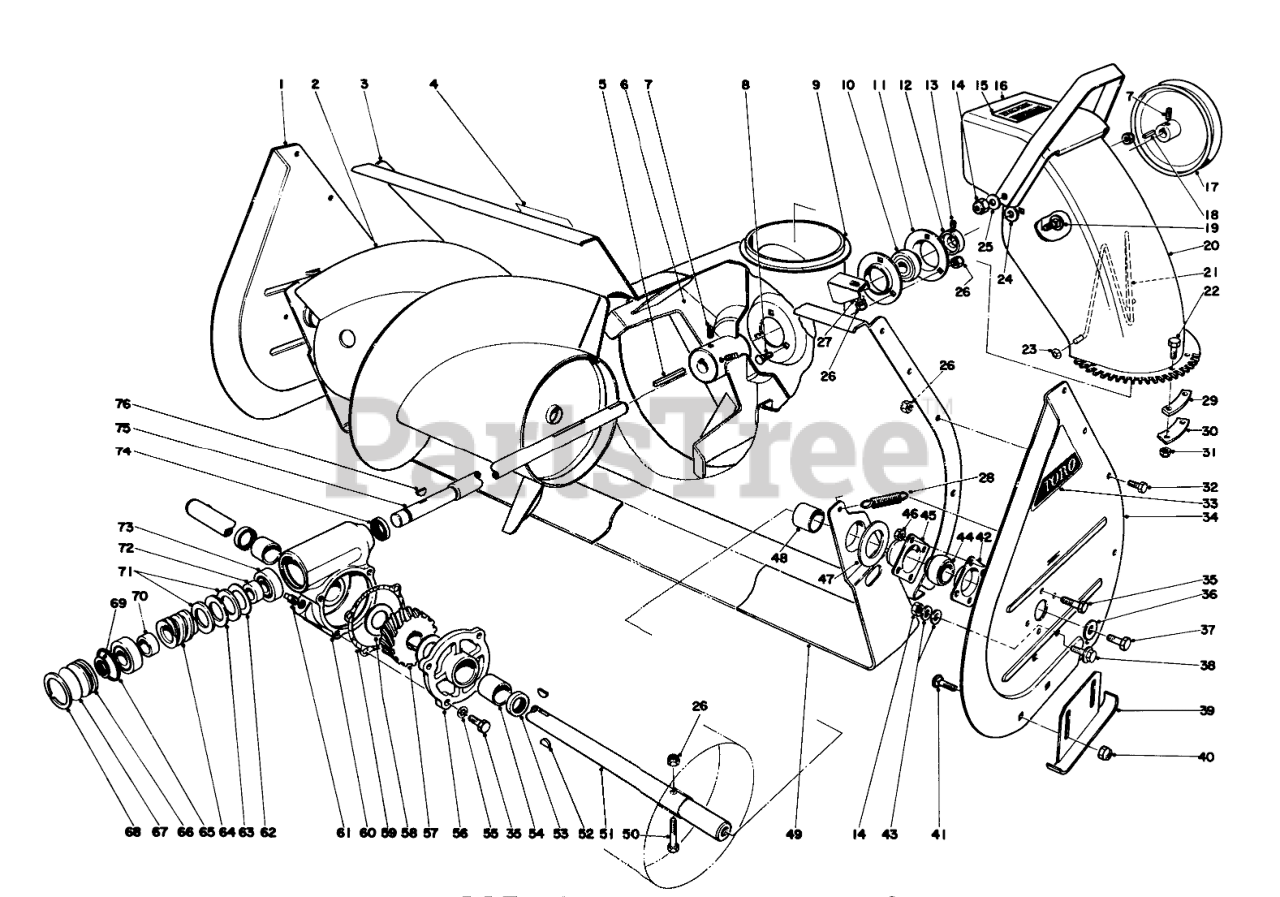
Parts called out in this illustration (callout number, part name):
7	Set Screw
8	BOLT-CARR
10	BALL BRG W/COLLAR
11	BRG FLANGE
12	EXT LOCKING COLLAR
13	SCREW-HSH
14	NUT-LOCK, CONE
18	SQUARE KEY
19	SCREW-CARR
21	WIRE-CHUTE
22	SCREW-HWH
23	NUT-PUSH
24	Rubber Washer
25	WASHER-BELLEVILLE
26	NUT-LOCK, CONE
27	WASHER-LOCK
28	SPRING-TENSION
30	CHUTE TAB SPACER
32	SCREW-HH
35	SCREW-HH
36	WASHER
37	SCREW-HH
38	SCREW-HHF
40	NUT-HHF, WHIZ
41	SCREW-CARR
42	BEARING-FLANGE, REAR
43	Washer
44	BEARING
45	BEARING-FLANGE, FRONT
46	NUT-LOCK, CONE
47	SCRAPER BLADE SPACER
48	50 Spacer
49	SCRAPER BLADE 32" *R
52	KEY-WOODRUFF
53	SEAL-OIL
54	BUSHING
55	WASHER-LOCK
57	GEAR-WORM, 27T
58	WASHER-THRUST
61	PLUG-PIPE, SQH
65	O-RING
68	INTRNL RETAINING RING
69	RING-SNAP
73	.750 BALL BEARING
74	SEAL-OIL
75	WORM SHAFT
76	KEY-WOODRUFF
